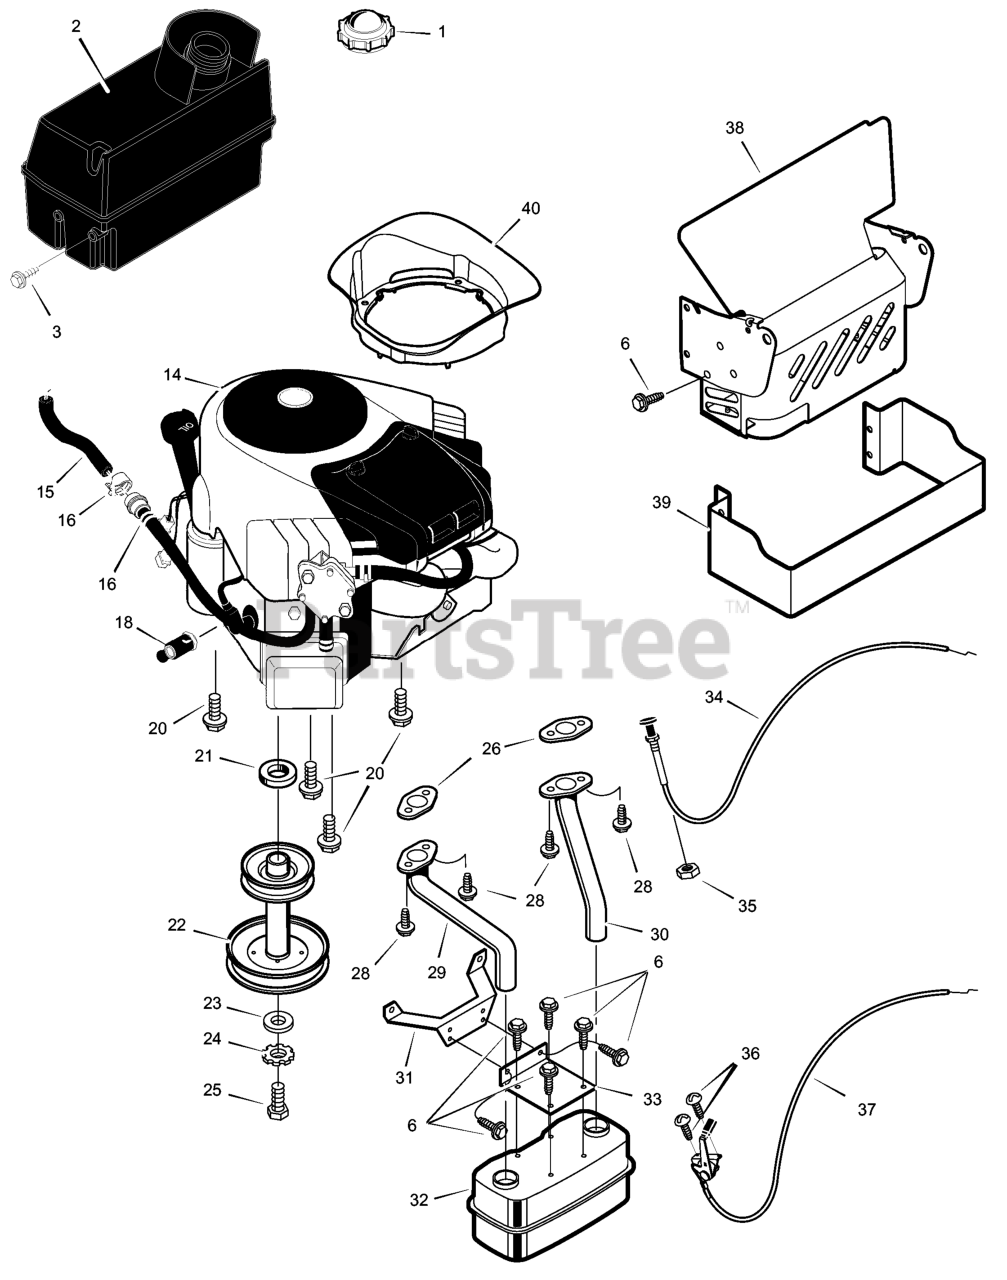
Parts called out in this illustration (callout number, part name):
1	Cap, Fuel
2	Tank, Fuel
14	Engine *
15	Fuel Line (Must cut to length)
16	Clamp
18	Drain, Oil
20	Bolt
22	Pulley, Stack
24	Lockwasher
27	Washer
29	Tube, Right Exhaust
30	Tube, Left Exhaust
31	Bracket, Muffler Mount
32	Muffler
33	Bracket, Muffler
35	Nut
37	Control, Throttle
38	Shield Assembly, Heat
39	GUARD, Heat Shield
